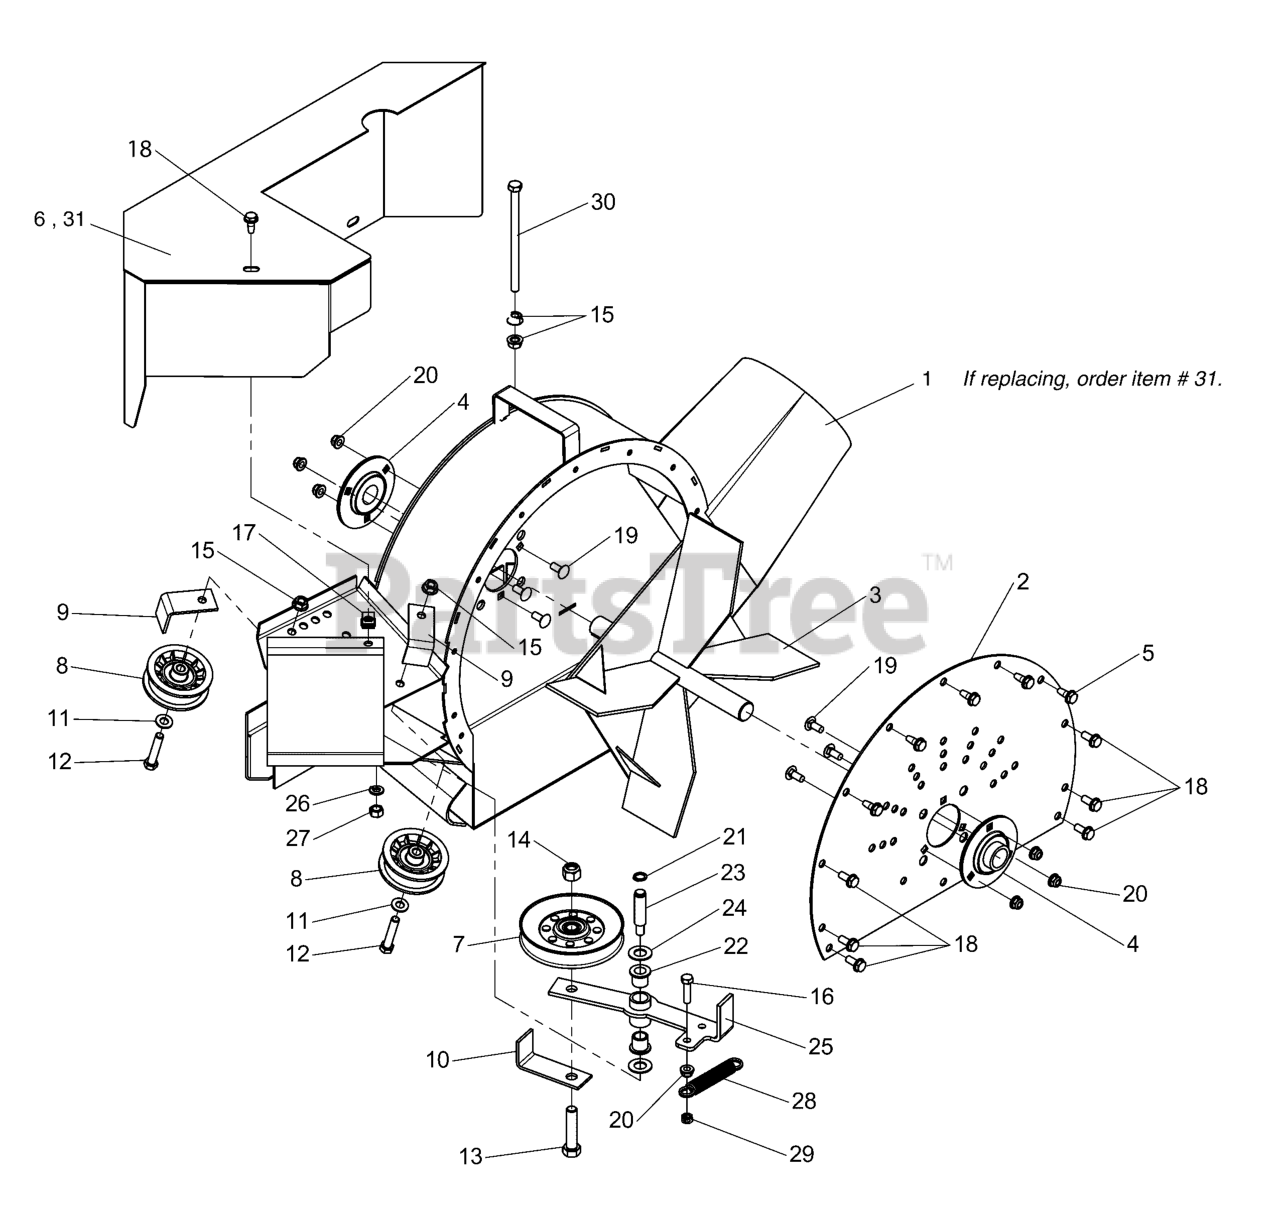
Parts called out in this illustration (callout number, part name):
1	WELD, BLOWER HOUSING - FAST VAC - BLK
2	PLATE, BACK - BLK
3	WELD, IMPELLER, FAST VAC BLOWER
3	WELD, IMPELLER, FAST-VAC BLOWER
4	BEARING, FLANGE, 1" Bore
5	BOLT, 5/16-18 X 3/4" Self Tap
6	WELD, BELT GUARD, BLOWER - BLK
7	PULLEY, IDLER V-NOTCH, 5"
8	PULLEY, IDLER, 2.75"OD X .37"ID, INSERT
9	KEEPER, BELT - BLK
10	RETAINER, BELT - BLK
11	WASHER, 3/8 SAE
12	BOLT, 3/8-16 X 2, GD5, CZ
13	BOLT, 1/2-13 X 2-1/4" GD5 CZ
14	NUT, 1/2-13 HEX NYLON LOCK
15	NUT, 3/8-16 HEX SERRATED FLANGE
16	BOLT, 5/16-18 X 1-1/4 GD5 YZ
17	BODY CLIP, 5/16-18-7GA MATERIAL
18	BOLT, 5/16-18 X 5/8" Self Lock
19	BOLT, 5/16-18 X 3/4", CARRIAGE
20	NUT, 5/16-18 HEX NYLOCK FLANGE
21	RETAINING RING, 1/2"
22	FLANGE BEARING, 9/16"
23	IDLER STUD
24	FLAT WASHER, 9/16" Narrow
25	WELD, IDLERARM, FAST-VAC - BLK
26	WASHER, 3/8" SPLIT LOCK
27	NUT, 3/8-24 HEX
28	SPRING, Extension
29	NUT, 5/16-18 Hex Center Lock
30	BOLT, 3/8-16 X 6" GD5 CZ
31	WELD, Fast-Vac Guard - BLK
